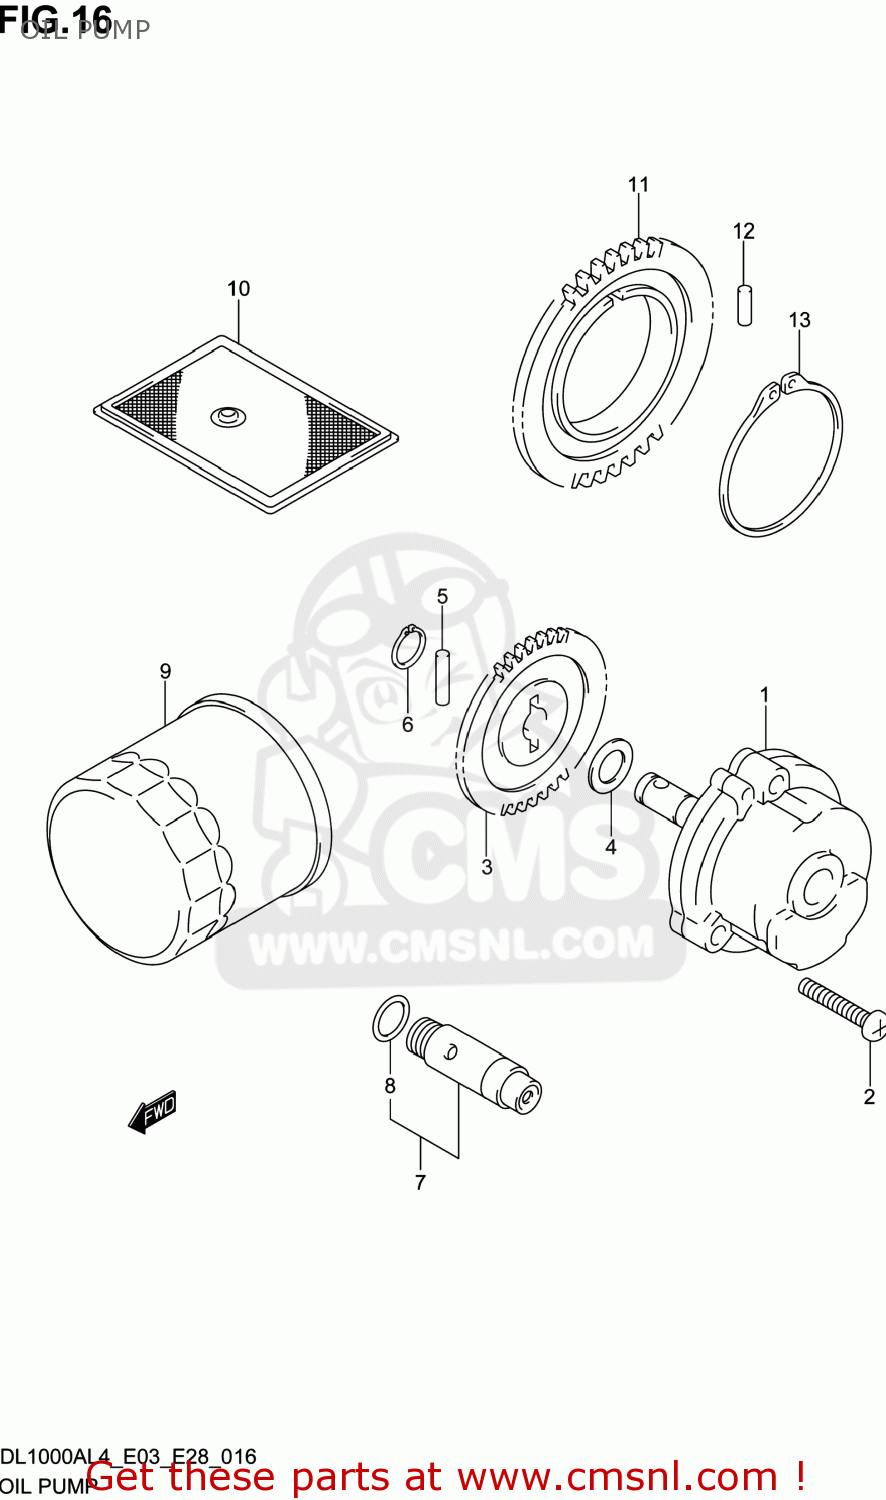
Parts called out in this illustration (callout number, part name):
1	PUMP ASSY,ENGINE OIL
2	BOLT
3	GEAR,OIL PUMP DRIVEN
4	SHIM(10X18X0.5)
5	PIN(4X15.8)
6	CIRCLIP
7	VALVE ASSY,OIL RELIEF(7K)
8	O RING(D:1.9,ID:13)
9	FILTER ASSY,ENGINE OIL
10	STRAINER,ENGINE OIL
11	GEAR,ENG OIL PUMP DRIVE
12	PIN(6X6)
13	CIRCLIP
